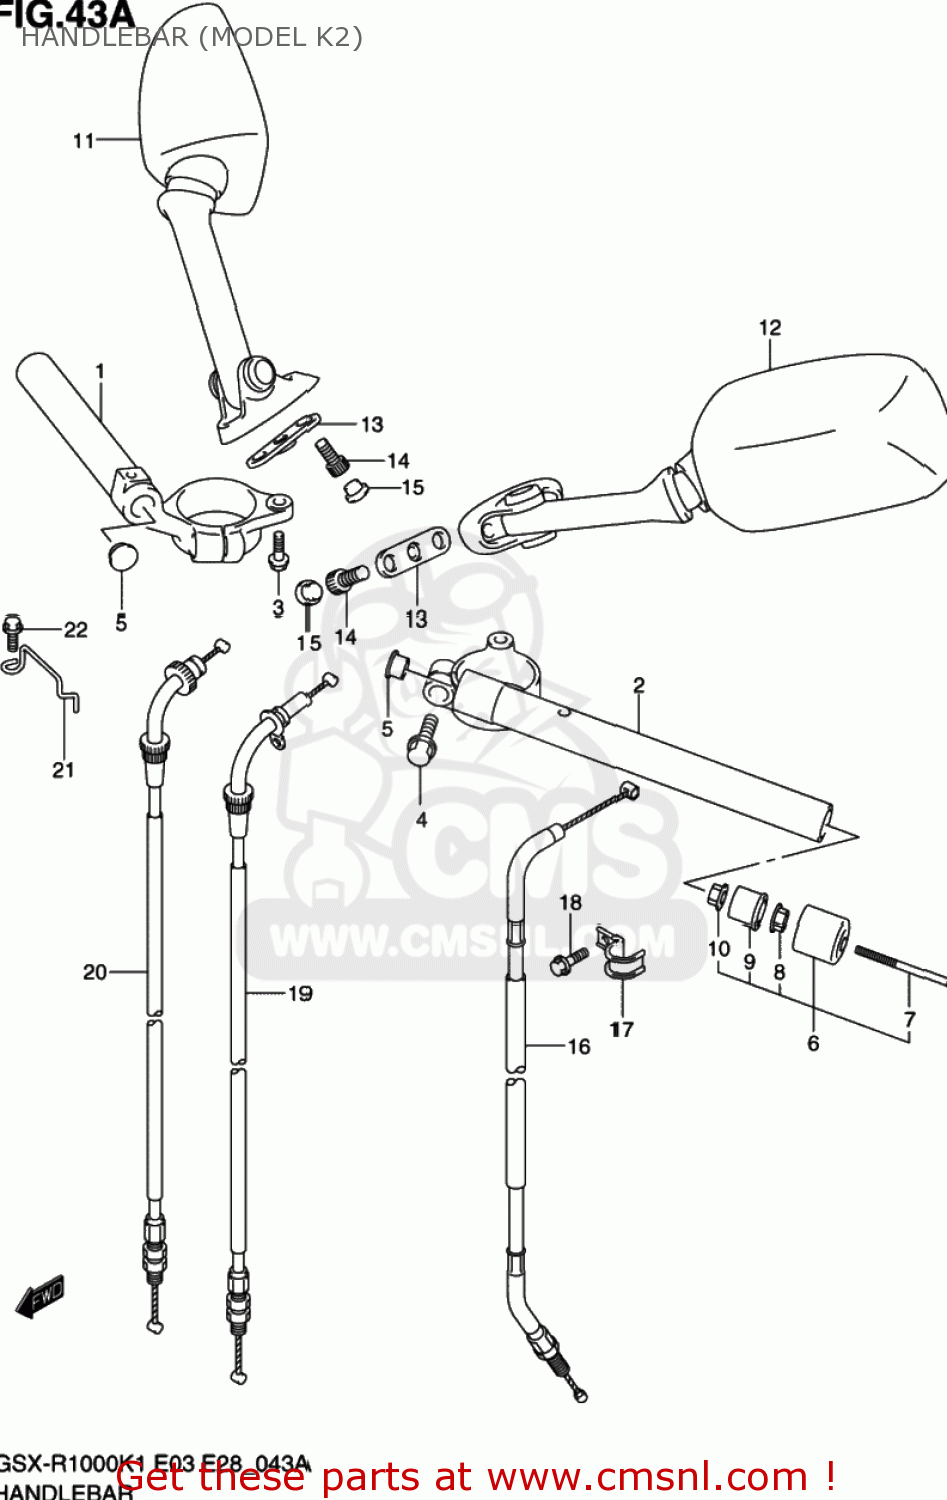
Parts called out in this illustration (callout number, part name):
1	HANDLEBAR,R
2	HANDLEBAR,L
3	BOLT
4	BOLT,HANDLEBAR
5	PLUG(OD:17)
6	BALANCER,HANDLEBAR
7	SCREW
8	NUT
9	EXPANDER,HANDLE BALANCER
10	NUT
11	MIRROR ASSY,RR VIEW,R
12	MIRROR ASSY,RR VIEW,L
13	CUSHION,RR VIEW MIRRORR
14	BOLT
15	CAP(OD:10)
16	CABLE ASSY,CLUTCH
17	GUIDE,CLUTCH CABLE
18	BOLT
19	CABLE ASSY,THROTTLE NO.1
20	CABLE ASSY,THROTTLE NO.2
21	GUIDE, CABLE
22	BOLT
